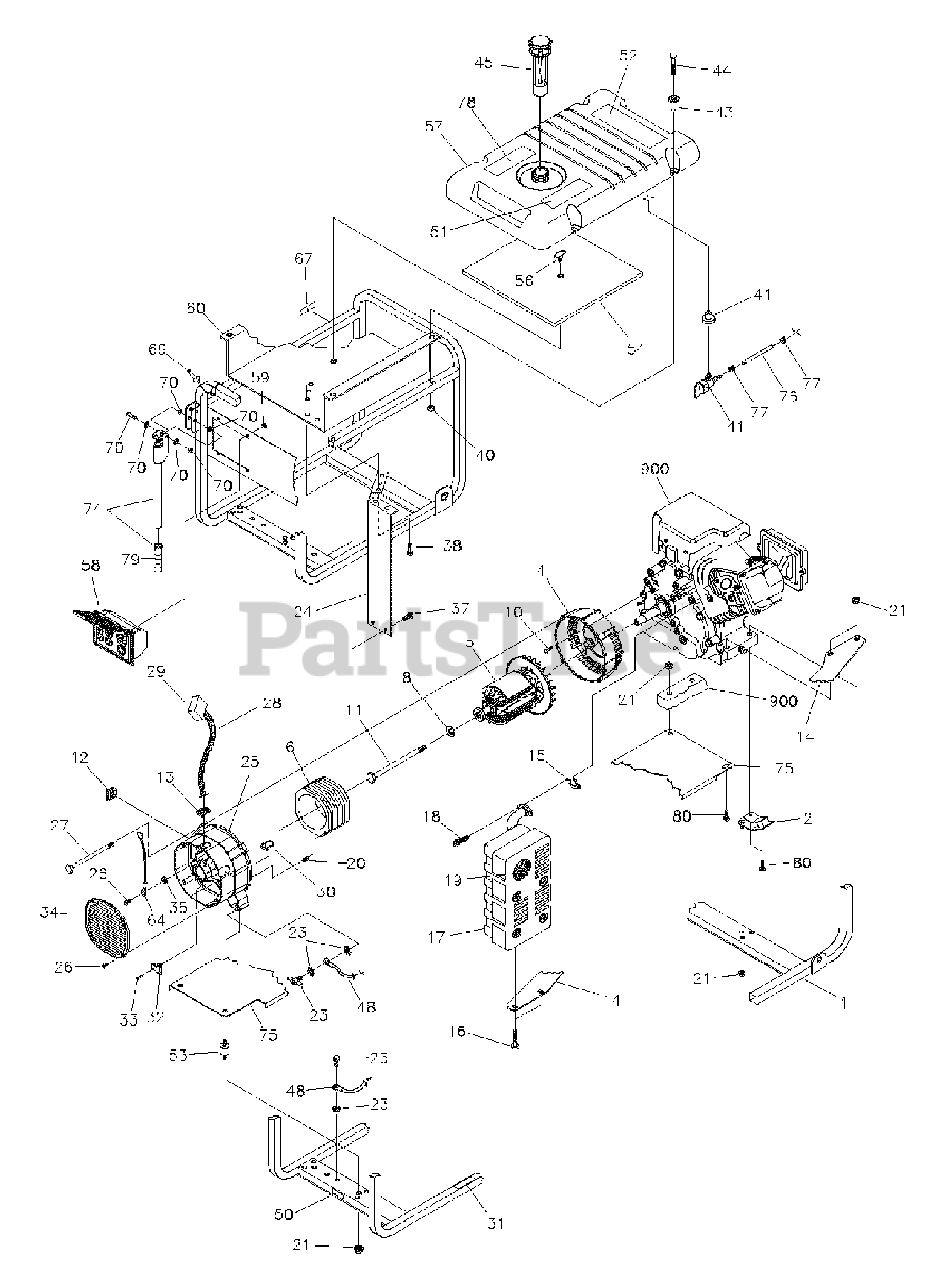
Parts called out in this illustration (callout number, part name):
1	CRADLE
2	MOUNT, Vibration
4	HOUSING, Engine Adapter
5	ASSY, Rotor
6	ASSY, Stator
12	GROMMET, Rubber
13	GROMMET, Rubber
14	BRACKET, Muffler
15	GASKET, Exhaust
16	SCREW, w/Lock Washer
19	SCREEN, Spark Arrest
20	PIN, Roll
23	KIT, Grounding Hardware
24	SHIELD, Heat
25	CARRIER, Rear Bearing
28	SLEEVING, Flexo
29	FASTEN, On Tab Housing 6P
30	GROMMET, Plastic
31	DECAL, Hot Muffler
32	ASSY, Brush Holder
33	SCREW
34	COVER, Bearing Carrier
40	NUT, Lock
41	KIT, Valve, Fuel Tank
43	GROMMET, Tank
45	CAP, Fuel Gauge
48	WIRE, Ground
50	DECAL, Ground, Green
51	DECAL, Danger
52	DECAL, Start Instructions
53	MOUNT, Vibration
54	INSULATION
56	CLIP, Insulation
57	ASSY, Tank, Fuel 7-Gallon
58	ASSY, Control panel (see page 19)
59	NUT, Palnut
60	SHIELD, Heat
64	WIRE, Ground, Panel
67	DECAL, Fuel Shut-off
69	PIN, with Lanyard
70	KIT, Fold Down Handle Hardware
74	ASSY, Handle (Includes Item 79)
75	PLATE, Stiffener
76	HOSE, Fuel
77	CLAMP, Hose
78	DECAL, Instruction, Fuel Level
79	GRIP, Handle
80	SCREW
900	ENGINE, NSP
